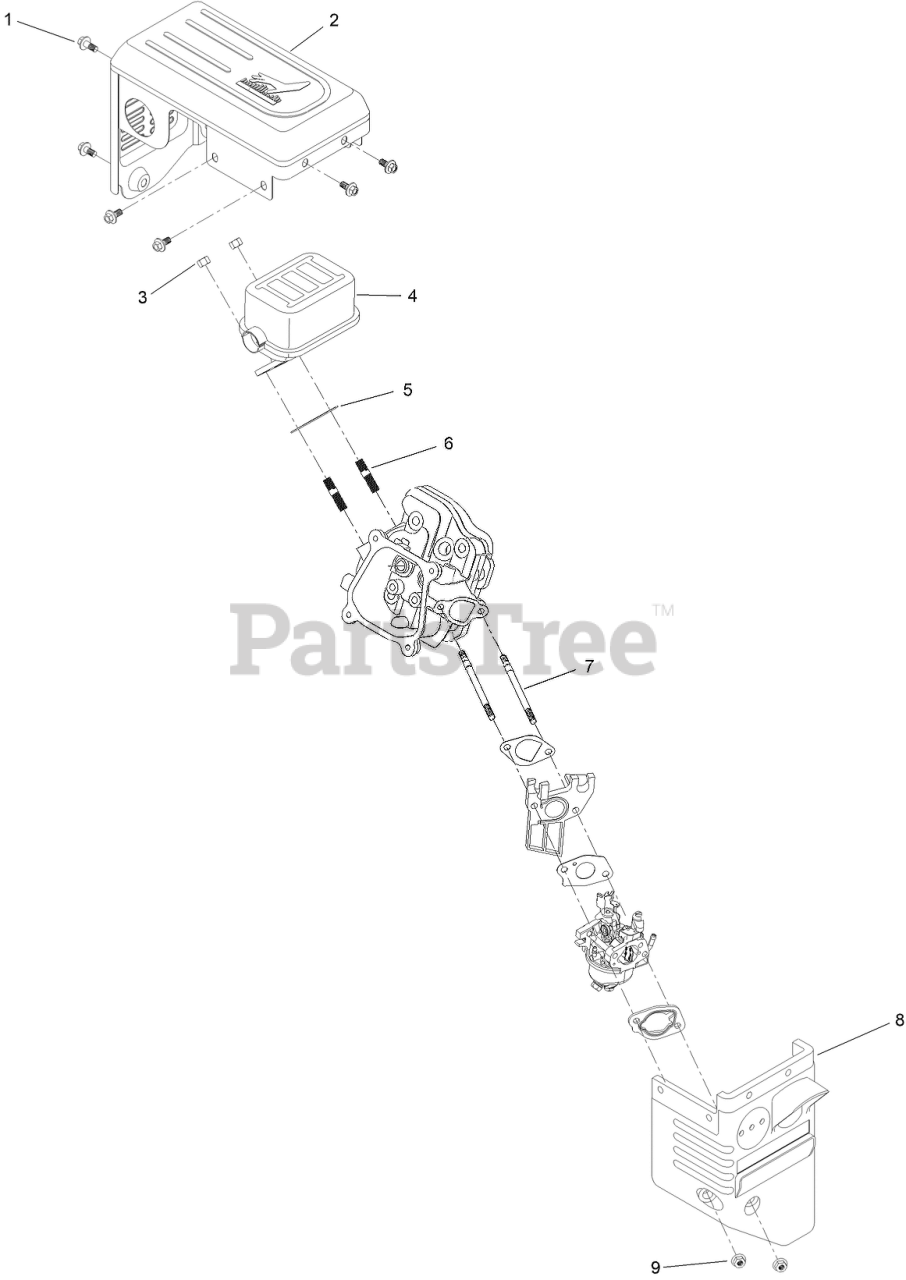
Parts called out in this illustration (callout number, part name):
1	SCREW-HHF
2	GUARD-MUFFLER
3	NUT-HH
4	MUFFLER ASM
5	GASKET-EXHAUST
6	STUD-EXHAUST
7	STUD-INTAKE
8	BOX-HEATER
9	NUT-FLANGE
